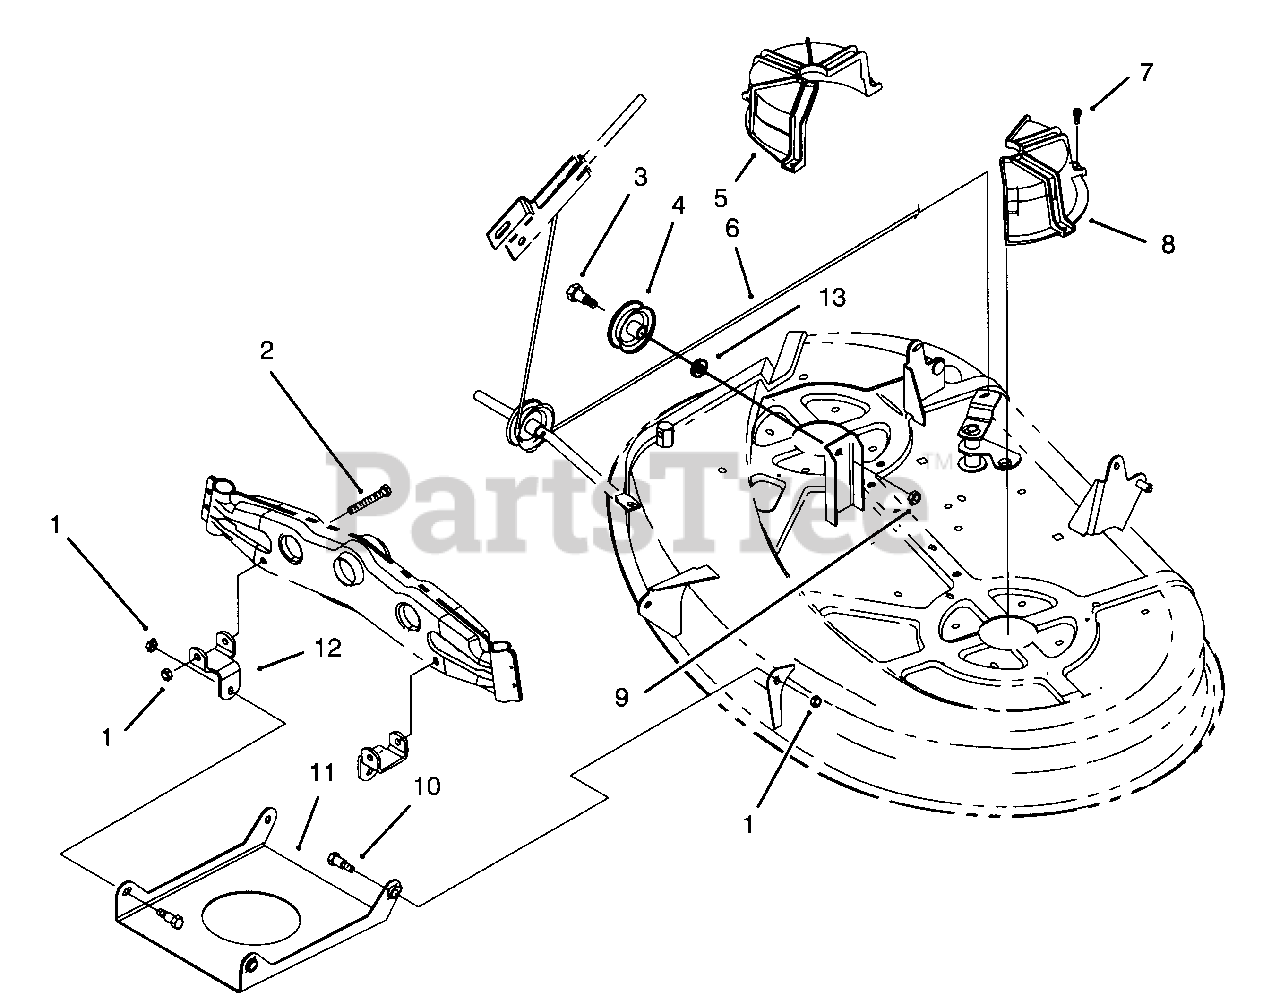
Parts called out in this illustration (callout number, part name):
1	Nut-Lock
2	Screw-Hex Hd. Cap
3	Bolt-Shoulder
4	Pulley-Cable
5	Guide-Deck Belt R.H.
6	Cable-Deck Engage
7	Screw-Thread Cutting
8	Guide-Deck Belt L.H.
9	Nut-Lock
10	Bolt-Shoulder
11	Pan-Front Deck Suspension
12	Bracket-Deck Suspension
13	Washer-Flat
